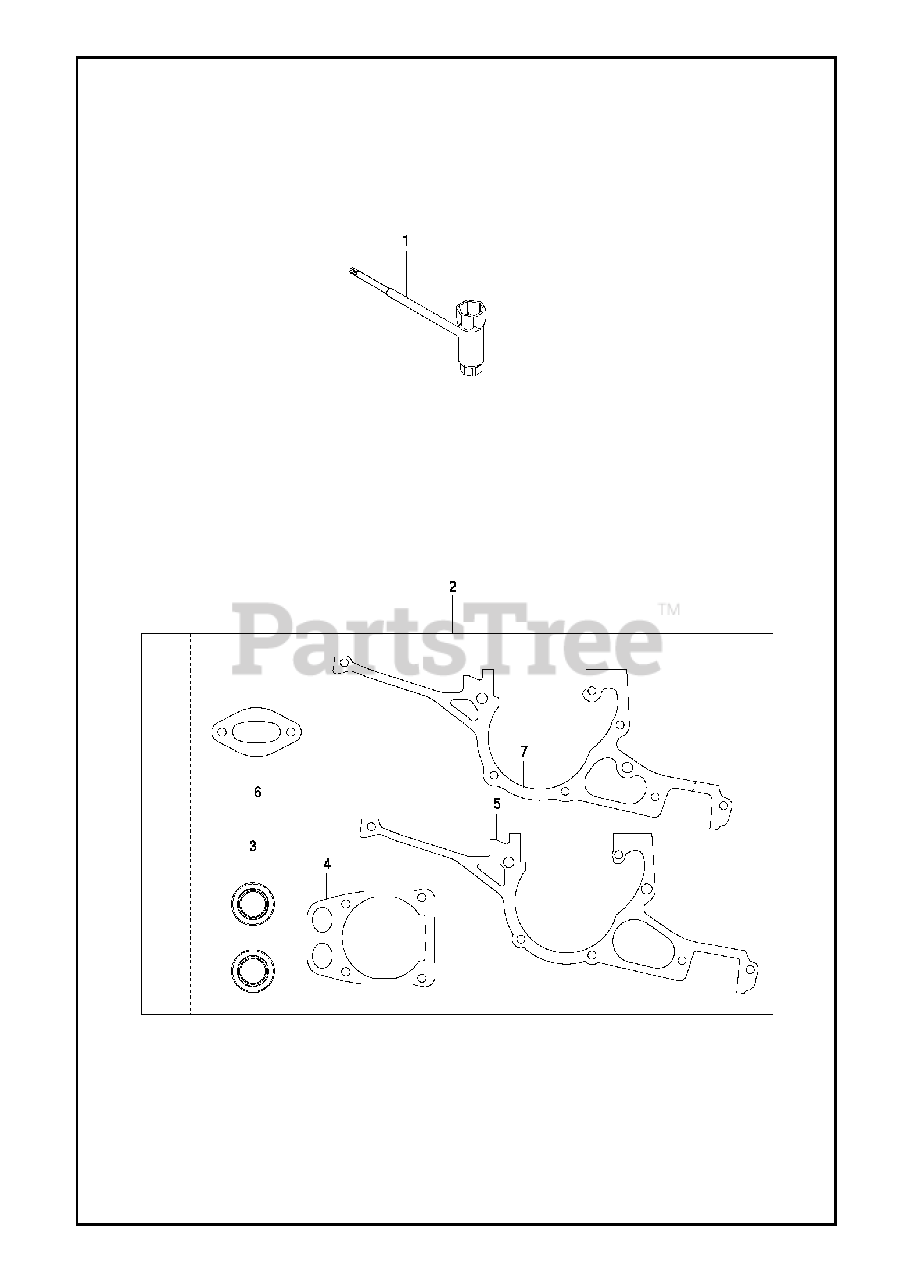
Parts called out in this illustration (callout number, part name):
2	GASKET KIT
3	SEALING RING
6	GASKET
